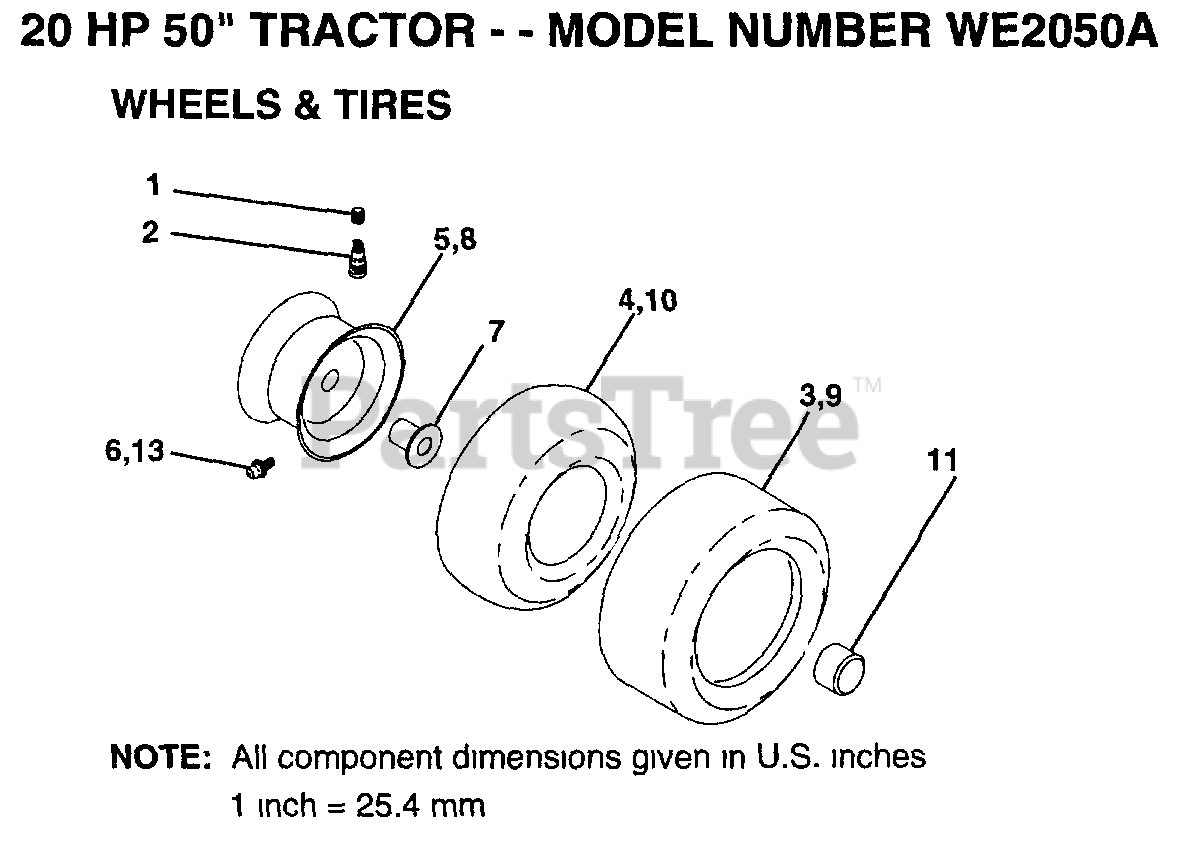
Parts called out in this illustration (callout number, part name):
1	VALVE CAP
2	VALVE STEM LT
4	TUBE.16X6.5/7.5-8
5	"RIM.FRONT.8"".YEL"
6	FITTING LT
7	"FLANGE, BEARING"
8	"RIM.REAR.12"".YEL"
10	TUBE.23X8/10-12
11	HUB CAP
13	ZERK FITTING M
